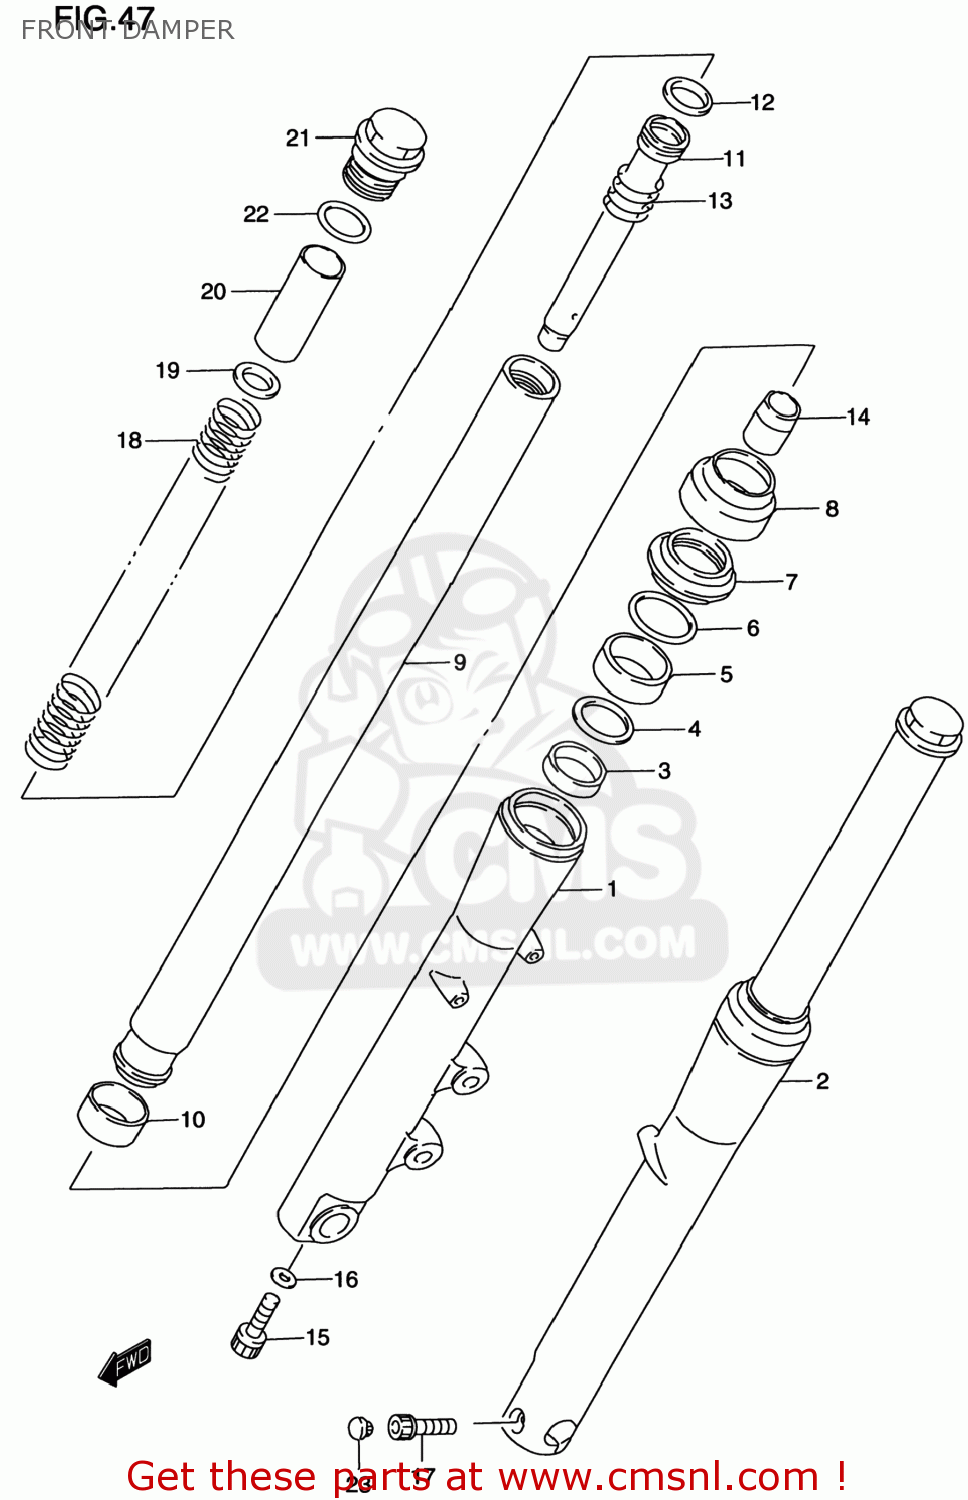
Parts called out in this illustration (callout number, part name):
1	TUBE,OUTER,R
2	TUBE,OUTER,L
3	BUSH,GUIDE
4	SPACER,SEAL
5	SEAL,OIL
6	RING,OIL SEAL STOPPER
7	SEAL,DUST
8	COVER,CASE
9	TUBE,INNER
10	BUSH,SLIDE
11	PIPE,SEAT
12	RING,PISTON
13	SPRING,REBOUND
14	PIECE,OIL LOCK
15	BOLT(8X27)
16	GASKET (NAS)
17	BOLT
18	SPRING
19	WASHER,SPRING
20	COLLAR,SPRING
21	BOLT,FORK
22	O RING
23	CAP(OD:14.5)
